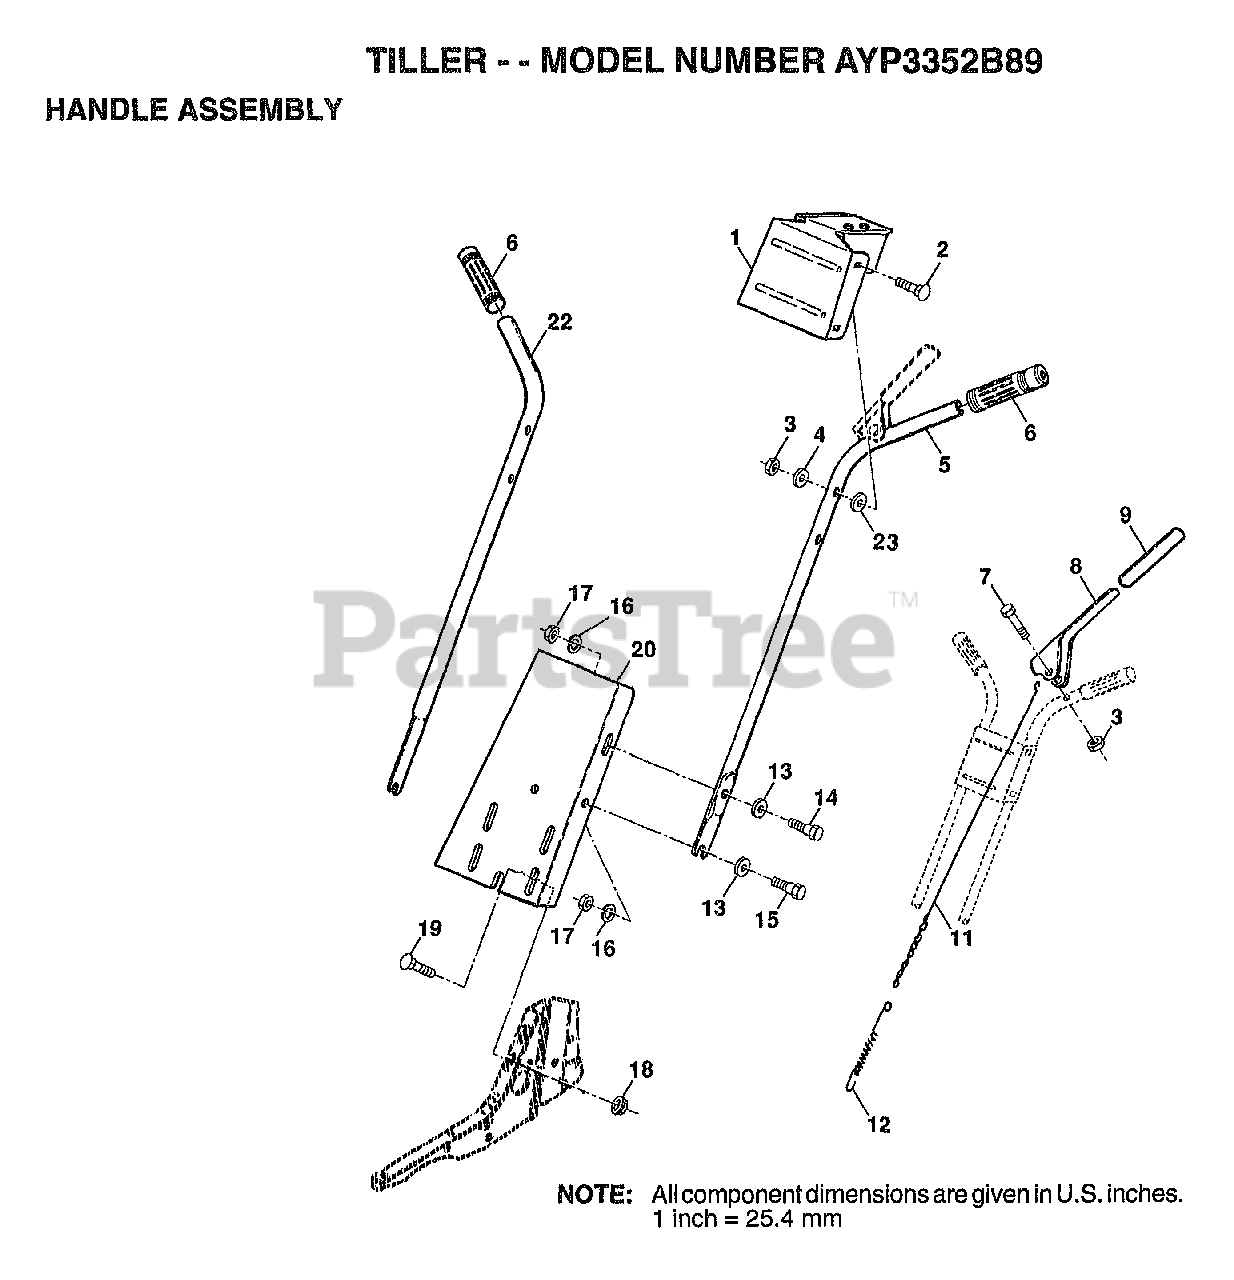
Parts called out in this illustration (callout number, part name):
1	HANDLE BRKT
2	BOLT
4	WASHER
5	HANDLE LH
7	BOLT.HEX.5/16-1.5
9	GRIP T
12	SPRING EXT TI
13	WASHER
15	BOLT
16	LOCKWASHER
17	NUT.HEX.5/16-18
18	NUT
19	BOLT
20	PANEL. HANDLE
22	HANDLE RH
23	WASHER
